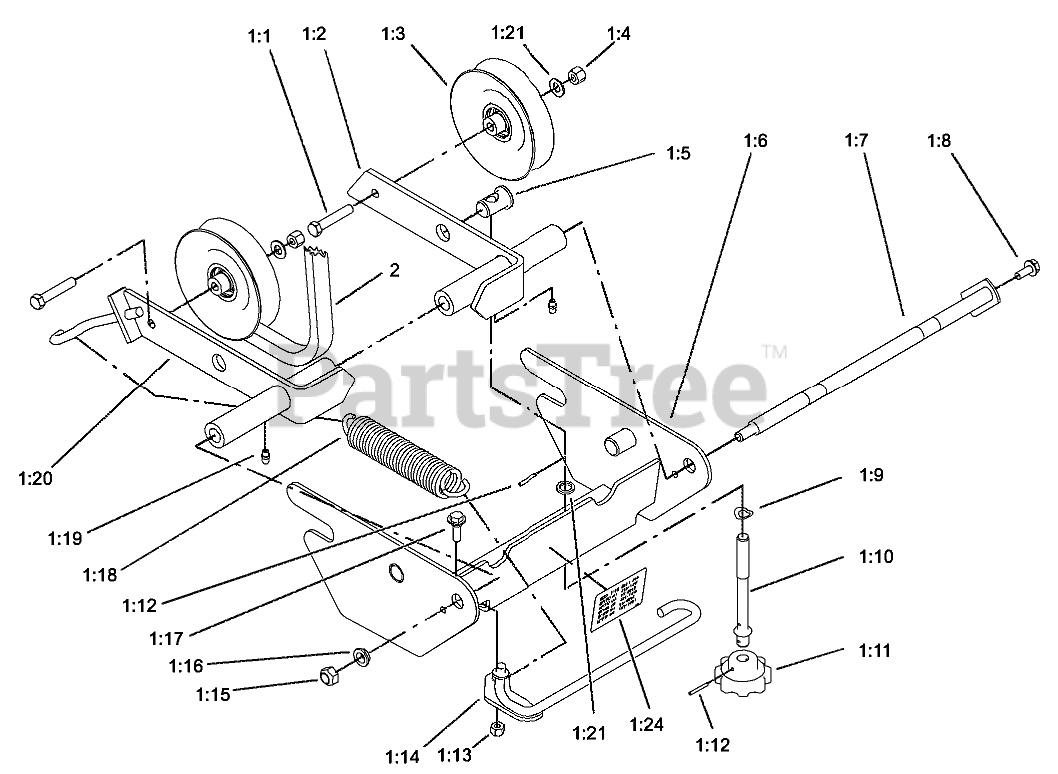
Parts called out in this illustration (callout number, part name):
1	PULLEY BOX ASM
1:1	SCREW-HH
1:2	LH Tension Bracket ASM
1:3	PULLEY-IDLER
1:4	NUT-LOCK, NI
1:5	Ferrule-Adjuster
1:6	Pulley Box ASM
1:7	ROD-PIVOT
1:8	SCREW-HWHTF
1:10	Rod-Tension
1:11	Knob-Adjusting
1:12	PIN-ROLL
1:13	NUT-LOCK, NI
1:14	TENSIONER-IDLER
1:15	NUT-LOCK, NI
1:16	Spacer-Shoulder
1:17	SCREW-SHOULDER
1:18	SPRING-EXTENSION
1:19	FITTING-GREASE
1:20	RH Tension Bracket ASM
1:21	WASHER-PLAIN
1:23	WASHER
1:24	DECAL-PULLEY BOX
2	BELT-V
